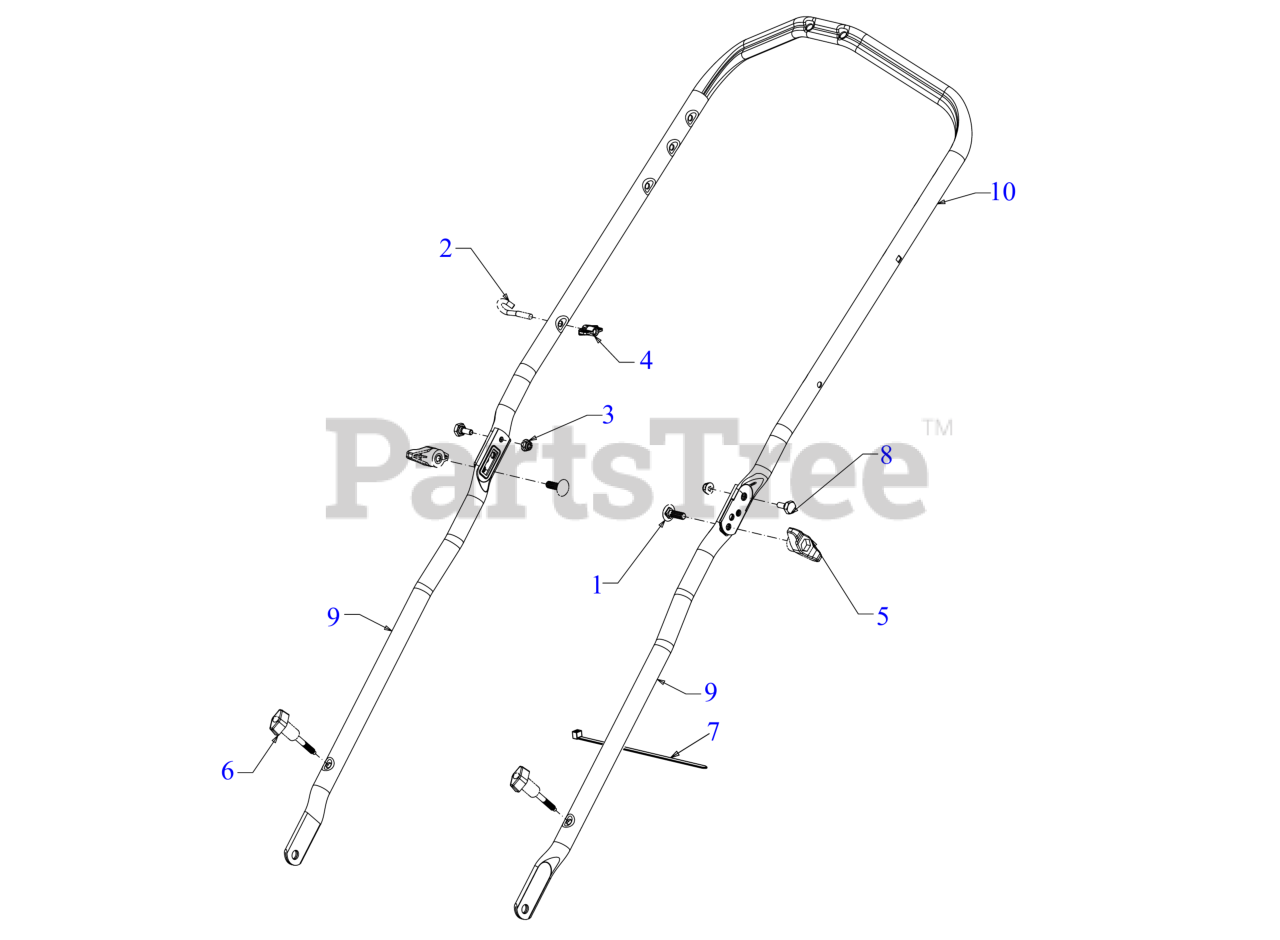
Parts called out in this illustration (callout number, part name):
1	SCREW 5/16-18 x 1.00 GR5
2	EYEBOLT 1/4-20
3	FLANGE LOCK NUT
4	HANDLE KNOB
5	STAR KNOB- RED
6	WING KNOB 1/4-20
7	7" CABLE TIE
8	SHOULDER SCREW
9	LOWER HANDLE (EZ FOLD)
10	UPPER ERGO HANDLE
